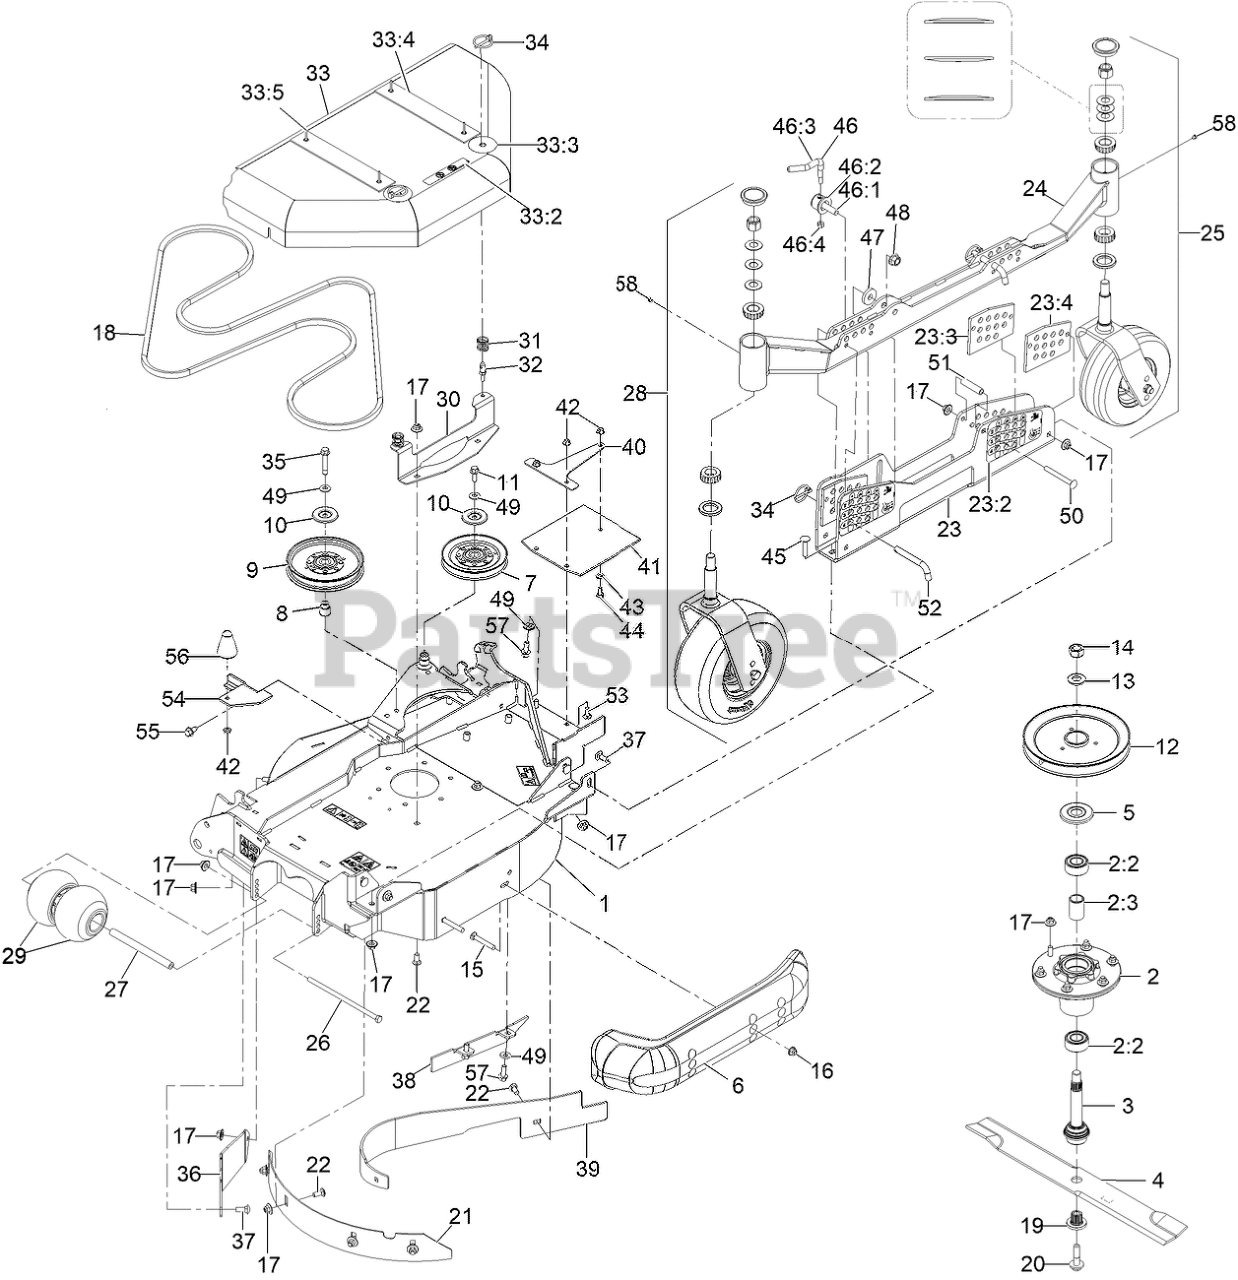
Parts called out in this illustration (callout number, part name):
1	ASM-DECK, LH WING 96
2	ASM-CUTTER HSG
2:2	BEARING-3205 TRASHGUARD
2:3	SPACER-BEARING
3	ASM-SPINDLE AND SEAL
5	GUARD-BEARING, TOP
6	SKID-BUMPER, DECK
7	IDLER-V
8	BUSHING-IDLER
9	IDLER-PULLEY
10	SHIELD-DUST
11	SCREW-HHF 3/8-16 X 1
12	SHEAVE-SINGLE 96RD
14	NUT-HEX
15	SCREW-CARR
16	NUT-HF, NI
17	Nut-Nyloc 3/8-16 Flg
19	BUSHING,SPLINED
20	SCREW,SEMS 1/2-20 X 2.19
21	BAFFLE-DEPTH, LH
22	BOLT-CARR
23	LH HOC CHANNEL ASM
23:2	DECAL-HEIGHT OF CUT-LH
23:3	PLATE-GUIDE, HOC (LH)
23:4	PLATE-GUIDE, HOC (RH)
24	TUBE-HOC, LH
25	Caster/Wheel ASM
26	SCREW-HH
27	SPACER-WHEEL
29	ROLLER-SCALP, ANTI
30	BRACKET-SHIELD MOUNT, OUT
32	PIN, SPRING
33	ASM-Wing Shield LH
33:2	DECAL-NO STEP
33:3	DECAL-SCRATCH COVER
33:4	Plate-Uhmw 2"
33:5	Rivet-Pop
34	PIN-LYNCH
35	SCREW-HHF
36	PLATE-FILL, LH DECK
37	BOLT-CARR
38	Fin-Baffle, Discharge Wing (LH)
39	BAFFLE-DOGLEG, CENTER (RH
40	SUPPORT-FLAP, LH
41	GUARD-TIRE, LH
42	NUT-HF, NI
43	WASHER-PLAIN
44	SCREW-HH
45	SCREW-CARR
46	LEVER ASM
46:1	SCREW-LOCK
46:2	CAP-LOCK
46:4	NUT-LOCK, NI
48	Nut-Lock 1/2-13
49	WASHER-BELLEVILLE
50	SCREW-CARR
52	PIN-HOC
53	BOLT-CARR
54	BRACKET-COVER RETAINER
55	SCREW-HWH
56	BUMPER-RUBBER
57	SCREW-HHF
